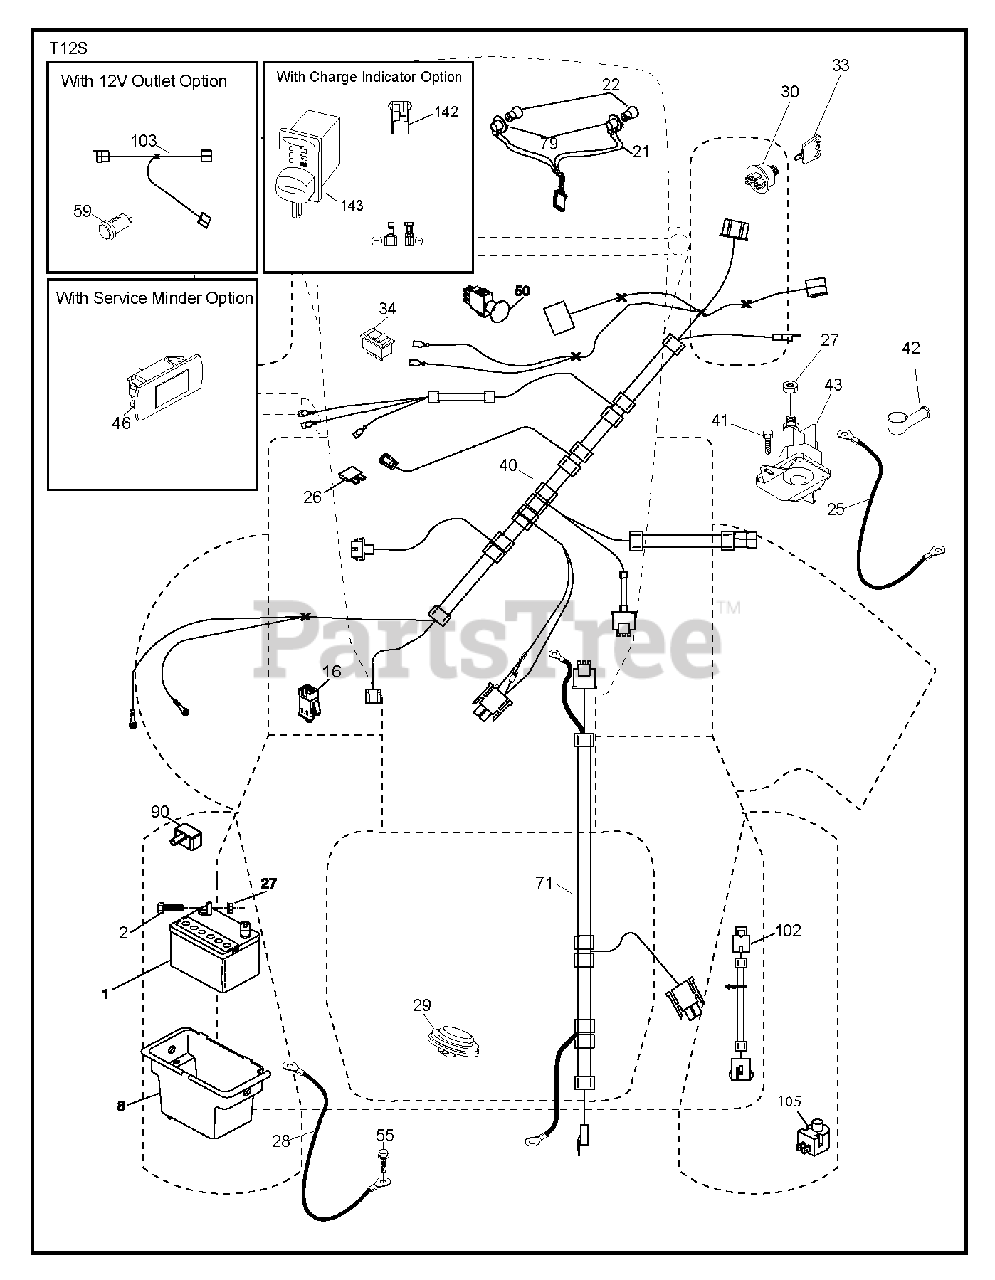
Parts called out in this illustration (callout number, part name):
1	Battery, Dry 30 Amp
2	BOLT.HEX.1/4.X.3/4.DICHROMATE
8	BOX.BATTERY.MNT.REAR.L
16	SWITCH INTERLOOK PUSH-IN
21	HARNESS.LIGHT W/4152J BULBS
25	CABLE.STARTER.6GA.BL/RED.14.
26	FUSE 20AMP
27	NUT
28	CABLE.BLACK.18"REAR.BA
29	SWITCH.SEAT.DELTA.OPC.
30	SWITCH.IGN.DELTA.W.LGH.ROS
33	KEY.CHAIN.BLISTER.PACK.GEN.INT
40	HARNESS.IGN.DASH.HUSQ/PRED
41	SCREW
42	TERMINAL COVER
43	SOLENOID.W/BRASS.PLUNGER
46	RP GUAGE.SRVCMNDR.HRMTR.
50	RB PTO.SWITCH.8 TERMINAL.BLACK
55	SCREW 5/16"
71	HARNESS.CHASSIS.TEX.8AWG
79	BULB HOLDER ASM.
90	COVER.TERMINAL.BATTERY
102	REVERSE SWITCH
105	HARNESS PIGTAIL PCH TEX ROS
142	CHARGE.PORT.PIGTAIL HARNESS
143	CHARGE.PORT
